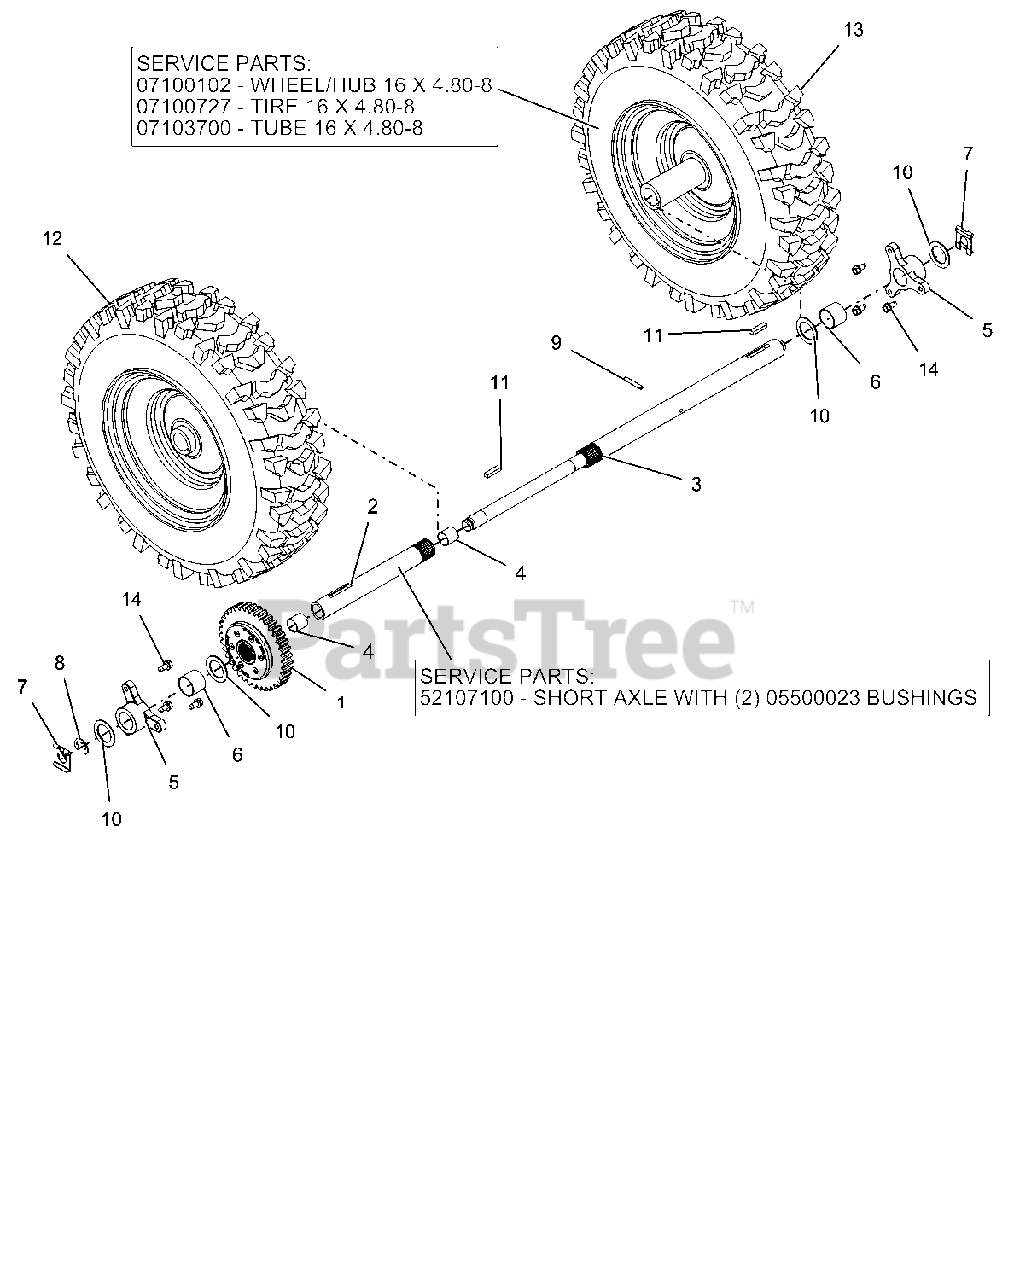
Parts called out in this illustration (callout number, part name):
1	DIFFERENTIAL, AUTOMATIC
2	BSHG-SLV .706X.764X.75 BRZ
2	KIT, SHORT AXLE W/BUSHINGS
3	AXLE, LONG - DIFFERENTIAL
4	BSHG-SLV .706X.764X.75 BRZ
5	BUSHING, AXLE
6	BSHG-SLV, 1.012X1.125X.875
7	CLIP, SNAP .625 DIA
8	RG-RTNG-EXT .625X.042
9	PIN-ROLL .188X1.25
10	WSHR-FL-STL 1.010X1.505X.062YZ
11	KEY-RECT .25X.188X1.00
12	TIRE/WHEEL,RH 16X4.8-8 DIFF T2
13	TUBE
13	HUB, WHEEL - 16X4.8-8 DIFF
13	TIRE/WHEEL,LH 16X4.8-8 DIFF T2
13	TIRE, 4.80-8 K478
14	SCR-TAP .25-20X.50 HWH TR YWZ
